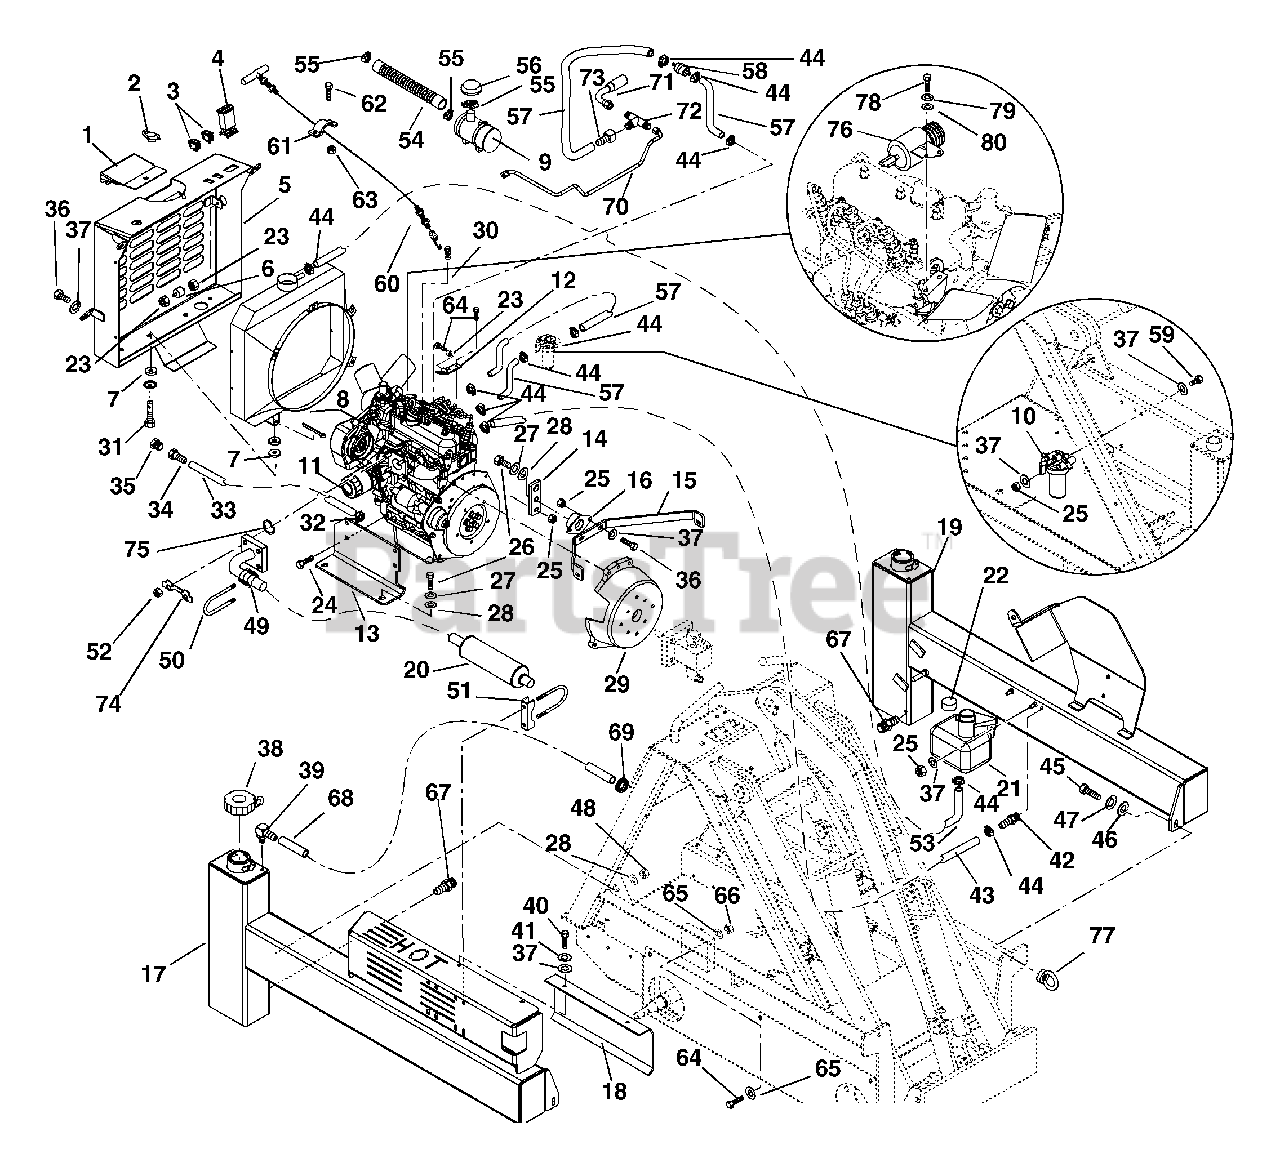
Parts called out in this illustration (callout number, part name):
1	Cover, Radiator Cap
2	Knob, Hand
3	Light Indicator
4	Hour Meter
5	Guard, Radiator
6	Mount, Stud/Plate
7	Isolator
8	Engine, Kubota (D722B-1 (REP))
9	Filter, Air-Diesel
10	Filter, Fuel-Kubota Diesel
11	Filter, Oil-Kubota Diesel
12	Bracket, Throttle Cable
13	Mount, Engine Right Hand Diesel
13	Mount, Engine Left Hand Diesel
14	Plate, Tie
15	Bracket, Upper Engine
16	Mount, Engine
17	Tank, Fuel Diesel Right Hand
18	Bracket, Muffler
19	Tank, Fuel Diesel Left Hand
21	Tank, Plastic 1.5 Quart
22	Cap, 1.62 Vented
23	Nut-Hex M6 x 1.0
24	Bolt, Hex M10-1.25 x 20
25	Nut-Locking-Nylon M8-1.25
26	Bolt-Hex .50-20X1.00 Grade 5
27	Washer-Locking .50 x .125
28	Washer-Flat-Steel .531 x 1.06 x .095
29	Housing, Bell Kubota Assembly
30	Swivel Assembly
31	Bolt,Hex M10-1.25X40 with Lock Hole
32	Clamp-Hose Worm .44/.78 x .53
33	Hose, Oil Drain
34	Adapter, Female Swivel .75-16F
35	Plug, Hose Swivel .75-16M
36	Bolt-Hex M8-1.25 x 20
37	Washer-Flat-Steel .344 x .688 x .065
38	Cap, Fuel Tank
39	Fitting, Barbed 90 Degree Elbow .125-27M x .25 I.D. Hose
40	Bolt-Hex M8 X 1.25 x 16
41	Washer-Locking .31 x .078
42	Fitting, Barbed .125-27M x .250 I.D. Hose
43	Gas Line-Bulk 1/4" I.D.
44	Hose Clamp
45	Bolt M10 x 1.5 x 40
46	Washer-Flat-Steel .406 x .812 x .065
47	Washer-Locking .44 x .109
48	Nut-Locking-Nylon M12-1.75
49	Pipe, Exhaust
50	Clamp, Muffler U-Bolt
51	Clamp, Muffler 3.50
52	Nut-Hex M8-1.25
53	Hose,5/16 I.D.
54	Hose, Flexible
55	Clamp, 2.25 Diameter Hose
56	Filter, Pre Diesel
57	Hose, .312 I.D.
58	Filter, Fuel .312 I.D. Hose
59	Bolt-Hex M8-1.25 x 65
60	Cable, Throttle-Diesel
61	Clamp, Cable
62	Bolt-Hex M5-.8 x 16
63	Nut-Locking-Nylon M5 .8
64	Bolt-Hex M6-1.0 x 25
65	Washer-Flat-Steel .281 x .62 x .065
66	Nut-Locking-Nylon M6-1
67	Adapter, Male Connector .562-19M x .125-27M
68	Gas Line-Bulk .25 I.D.
70	Tube-Fuel Line Long
71	Tube-Fuel Line Short
72	Adapter-Tee .56-18
73	Fitting-Hose .375-M6
74	Bracket, Lock
75	Washer, Wave
76	Solenoid
77	Nut, Eye M10-1.5
78	Bolt-Hex M6-1 x 16
79	Washer-Locking .25 x .062 Regular
80	Washer-Flat-Steel.312 x .734 x .065
